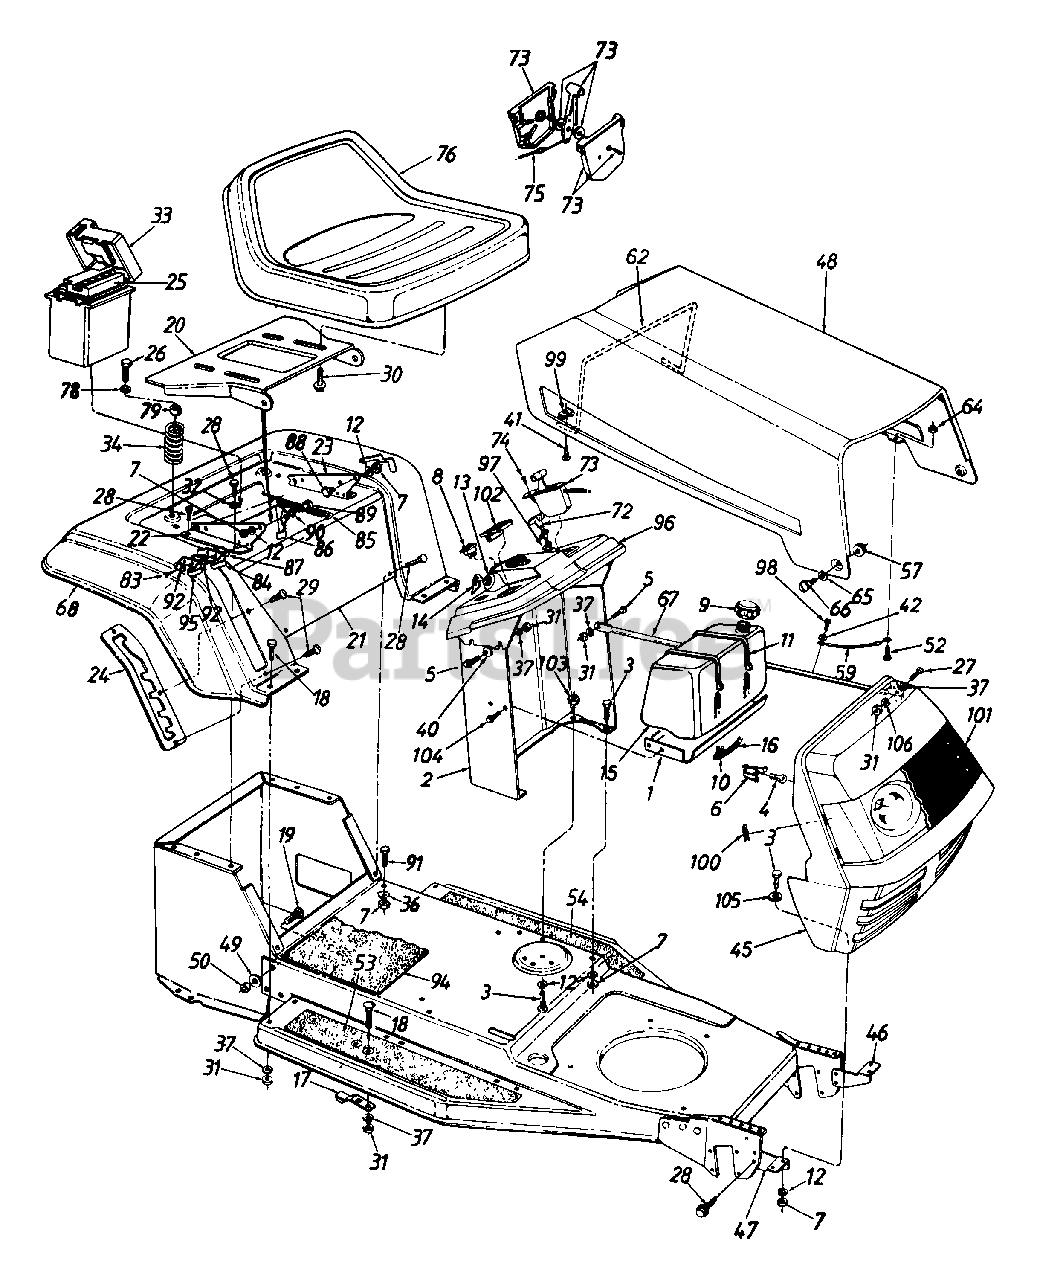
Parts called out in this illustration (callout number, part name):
3	Hex Bolt 5/16-18 x .75" Lg.
4	Bulb
5	Hex Bolt 1/4 x .62" Lg.
6	Socket
7	Hex Nut 5/16-18 Thd.
8	Light Switch
9	Gas Cap
10	Hose Clamp
11	Cable Tie
12	L-Wash. 5/16" I.D.
13	Ignition Switch
14	Ignition Key
15	Fuel Tank
16	Gas Line 15" Long
17	Blade Brake Ass'y.
18	Carriage Bolt 1/4-20 x .62"
19	Ribbed Neck Bolt 3/8-24 x .8"
20	Seat Pivot Brkt.
25	Battery
26	Hex Self-Tap Screw 5/6-18 x 1.25" Lg.
27	Truss Mach. Scr. 1/4-20 x .75" Lg.
28	Hex AB-Tap Scr. 5/16 x .75" Lg.
29	Torx Mach. AB-Tap Scr. 1/4 x .62" Lg.
30	Hex Self-Tap Scr. 3/8-16 x .75" Lg.
31	Hex Nut 1/4-20 Thd.
32	External L-Wash. 5/16" I.D.
33	Battery Box w/Cover
34	Compression Spring
36	Bell-Wash. 5/16" I.D.
37	L-Wash. 1/4" I.D.
40	Bell-Wash. .265" I.D. x .75"
41	Pan Hd. Scr. 10-24 x .75" Lg.
42	Fl-Wash. .218" I.D. x .62"
47	Grille Mtg. Brkt.- R.H.
50	Hex L-Nut 3/8-24 Thd.
52	Truss Mach. Scr. #10-24 x .5" Lg.
53	Foot Pad - R.H.
54	Foot Pad - L.H.
57	Lock Nut 1/4-28 Thd.
59	Hood Stop
62	Hood Spring
64	Hex Sems Nut #10-24 Thd
65	Spr. Wash. .39" I.D. x .62" O.D.
66	Shld. Bolt
72	Choke Control
73	Throttle Control Box
74	Truss AB-Tap Scr. #10 x .5"
75	Throttle Wire (B&S)
75	Throttle Wire (Tec.)
76	Seat Assembly (Low Back)
76	Seat Assembly (Medium Back)
76	Seat Assembly (High Back)
76	Seat Assembly (Low Back - Yellow)
78	Fl-Wash. 344" I.D x .88" O.D.
79	Bushing
83	Hex Tap Scr. #8 x .5" Lg.
84	Safety Switch (Seat)
85	Ext. Spring 5.31" Lg.
86	Seat Lift Brkt.
87	Insulator Boss Plate
88	Shld. Bolt .437" Dia. x .162" Lg.
89	Shld. Bolt .437" Dia. x .268" Lg.
90	Spr. Wash .445" I.D. x .75" O.D.
91	Hex Wash. Hd. Scr. 5/16-18 x .62" Lg.
92	Insulator Plate
94	Center Foot Pad
95	Safety Switch (Seat)
96	Dash Panel
97	Retainer Clip
98	Truss Mach. B-Tap Scr. #10 x .5" Lg.
99	Speed Nut
100	Internal Cotter Pin 5/16" Dia
101	Lens
102	Ammeter
103	Hex Jam Nut 5/16-18 Thd.
104	Hex Wash. Hd. Tap Scr. 1/4-20 x .5" Lg
105	Fl-Wash. .344" I.D. x 1" O.D.
106	Ext. L-Wash 1/4" I.D.
